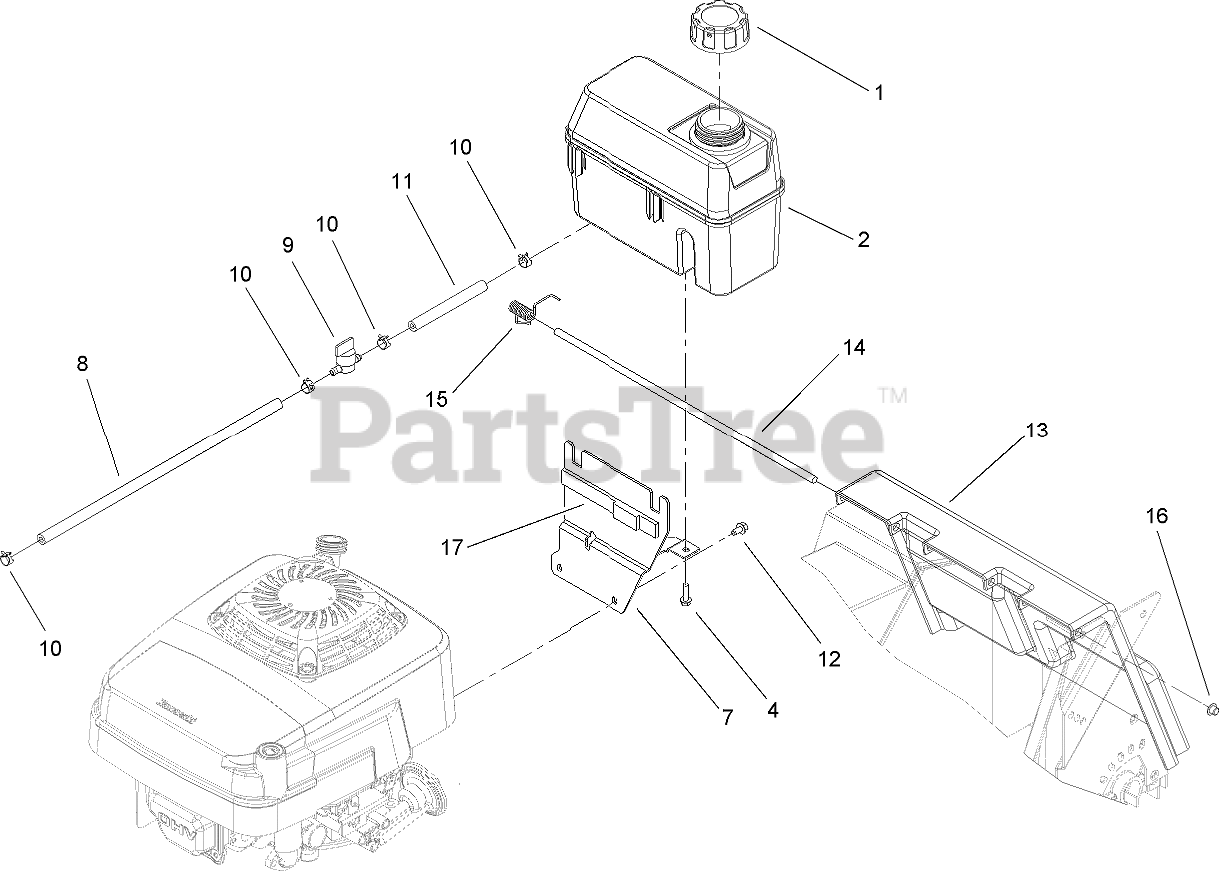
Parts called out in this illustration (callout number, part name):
1	CAP-GAS
2	Tank-Fuel
4	SCREW-HWH
7	TANK MOUNT ASM
8	HOSE-FUEL
9	VALVE-FUEL
10	CLAMP-HOSE
11	HOSE-FUEL
12	SCREW-HWH
13	DOOR-DISCHARGE, REAR
14	ROD-DOOR
15	SPRING-TORSION, DOOR
16	PUSHNUT-CAP, WASHER
17	DAMPER-RUBBER, TANK
